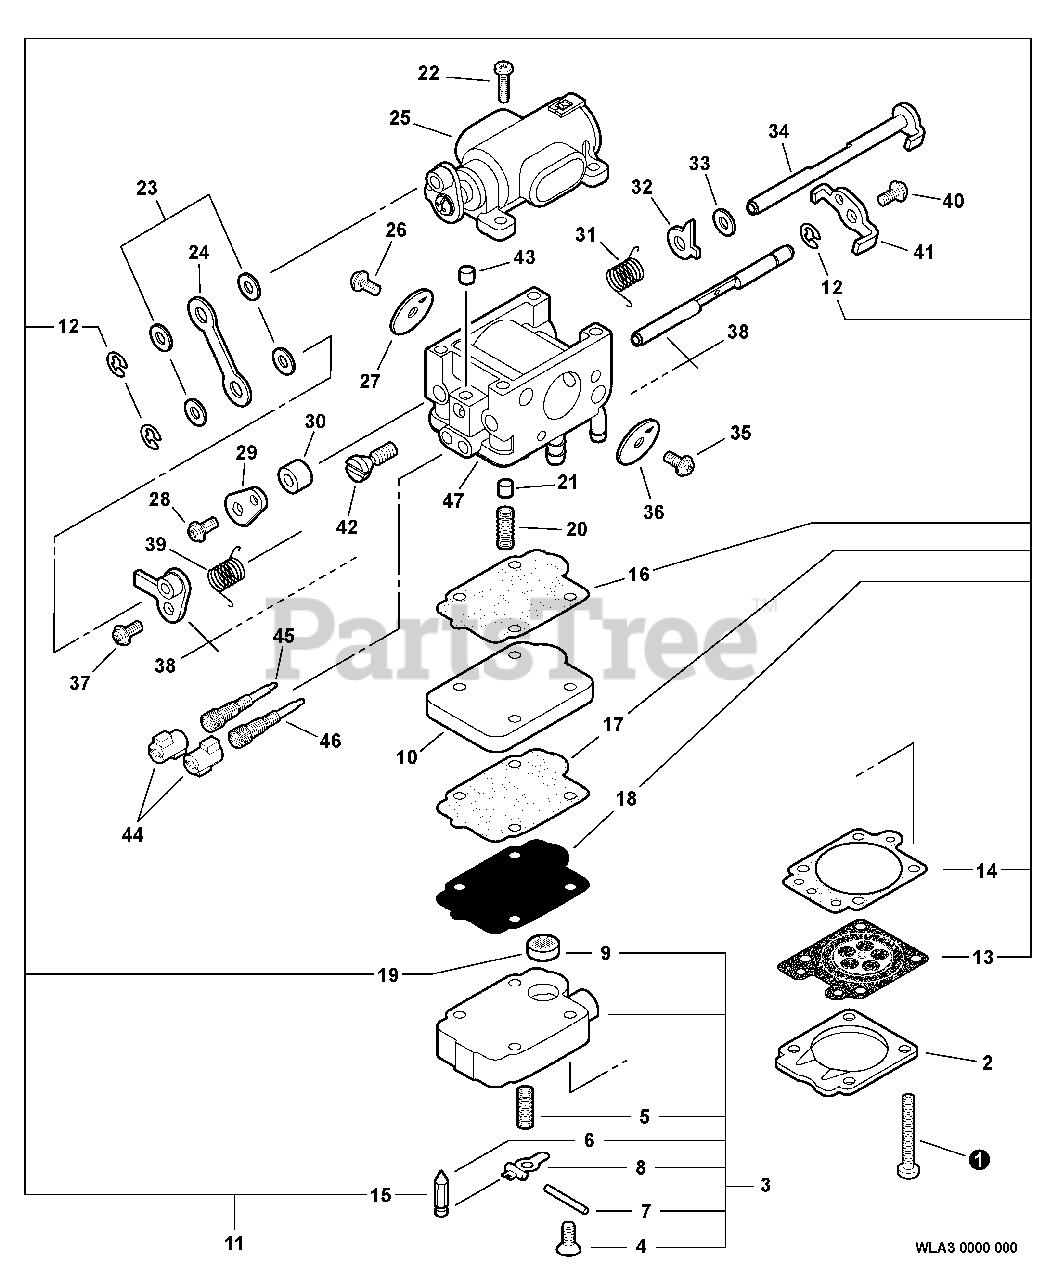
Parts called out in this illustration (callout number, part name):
2	COVER, METERING DIAPHRAGM
3	BODY ASSY, PUMP
5	SPRING, METERING LEVER
6	VALVE, INLET NEEDLE
7	PIN, METERING LEVER
8	LEVER, METERING
9	SCREEN, FUEL INLET
10	PLATE, PASSAGE
11	REPAIR KIT
13	DIAPHRAGM, METERING
14	GASKET, METERING DIAPHRAGM
15	VALVE, INLET NEEDLE
16	GASKET, PASSAGE
17	GASKET, PUMP
18	DIAPHRAGM, FUEL PUMP
19	SCREEN, FUEL INLET
21	PISTON ASSY
24	LINK, ROD
25	VALVE ASSY, AIR
27	VALVE, CHOKE
29	LEVER, CHOKE
32	LEVER, FAST IDLE
34	SHAFT ASSY, CHOKE
36	VALVE, THROTTLE
38	SHAFT ASSY, THROTTLE
41	LEVER, OUTER
42	SCREW, IDLE ADJUST
43	PLUG, FRICTION
44	CAP, LIMITER
45	NEEDLE, HIGH SPEED
46	NEEDLE, LOW SPEED
47	BODY, CARBURETOR
